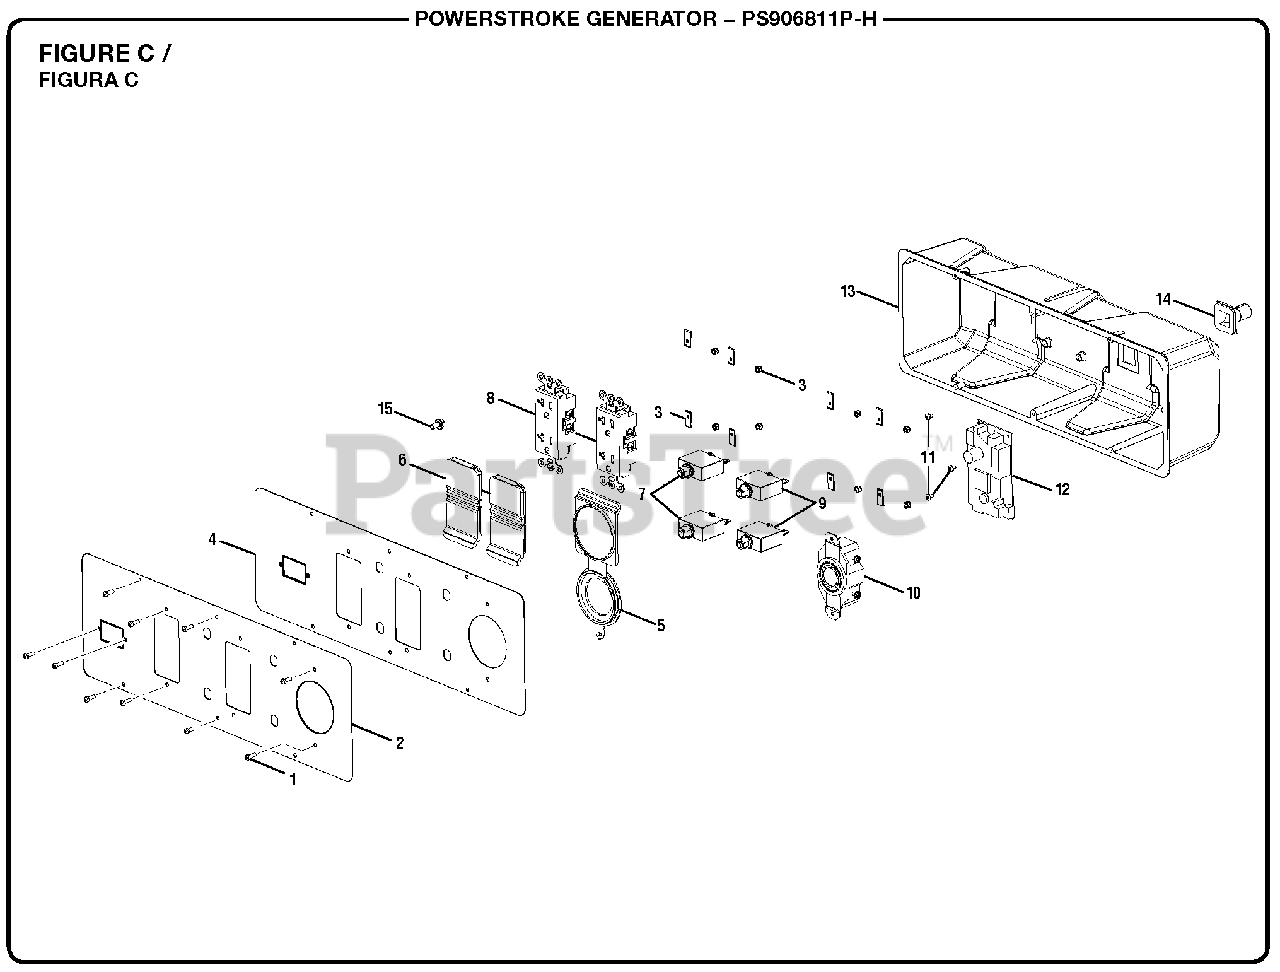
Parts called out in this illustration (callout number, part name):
1	Screw (6-20 x 3/8 in.)
2	Outlet Panel Label
3	U- Clip Nut (#6)
3	Nut (#6-32)
4	Front Panel
5	240 Volt Outlet Covers
6	120 Volt Outlet Covers
7	Circuit Breaker (30 Amp)
8	120 Volt Duplex Receptacle
9	Circuit Breaker (20 Amp, 125 Volt)
10	Twist Lock Receptacle (120/240 Volt, 30 Amp, L14-30R)
11	Screw (M3 x 5 mm,)
12	Battery Charger
13	Control Box (Back Panel)
14	Rubber Boot (Control Panel Assembly)
15	Bolt (M5 x 10 mm, Hex Hd.)
